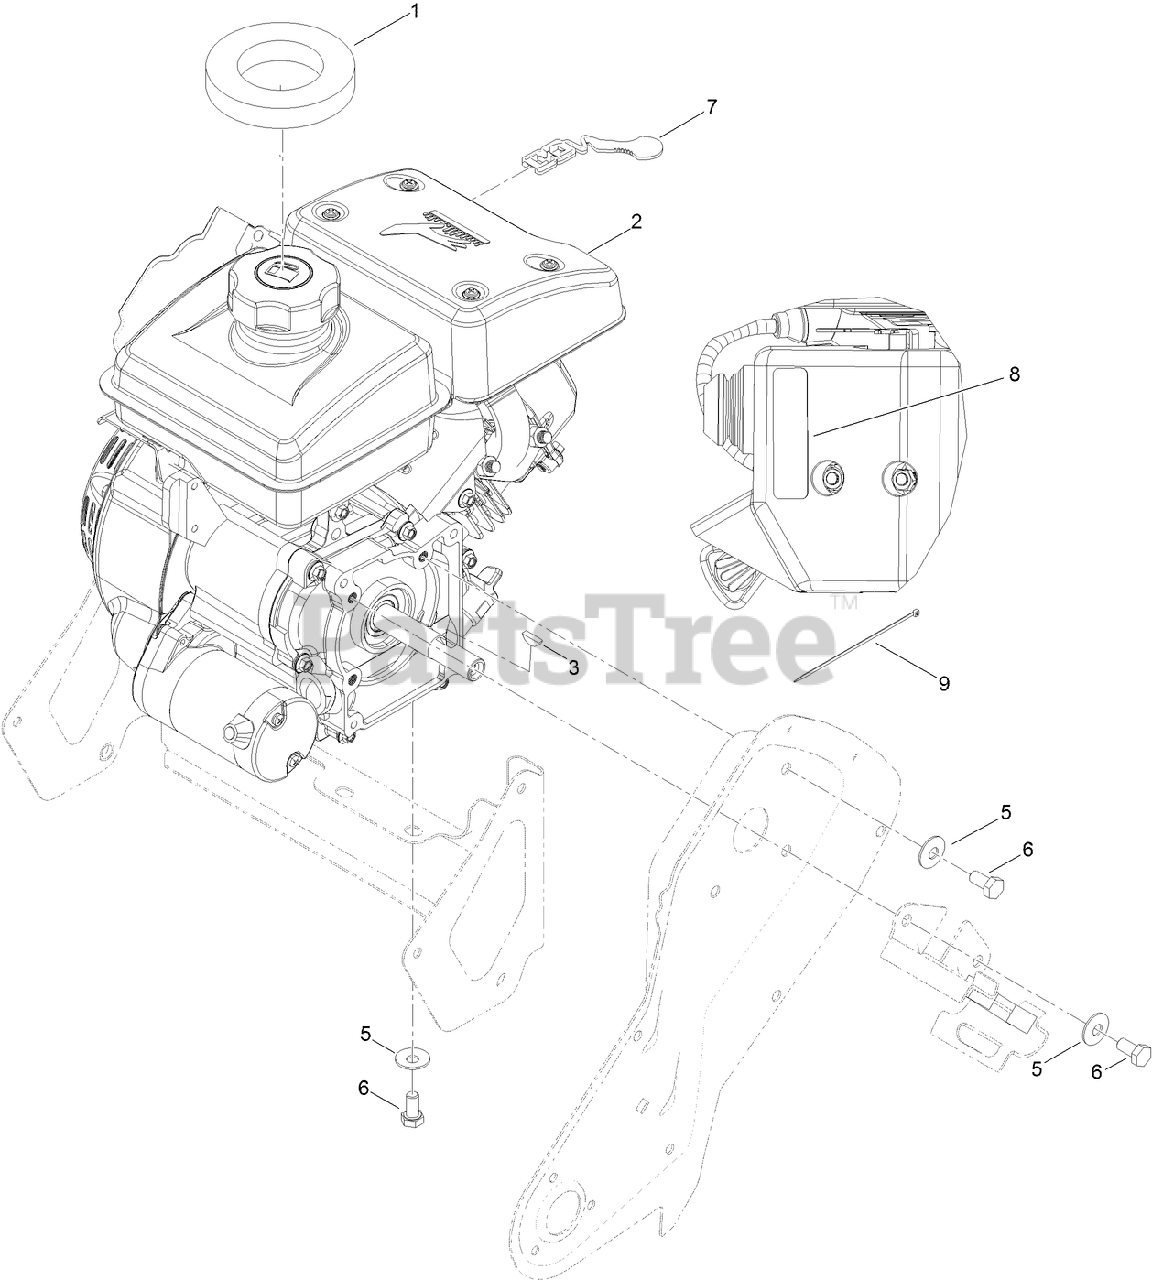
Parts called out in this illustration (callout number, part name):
1	SEAL-TANK
2	ENGINE-156FDS
3	KEY-WOODRUFF
5	WASHER-BELLEVILLE
6	SCREW-HH
7	LEVER-CHOKE
8	DECAL-CONTROLS, ENGINE
9	TIE-CABLE
